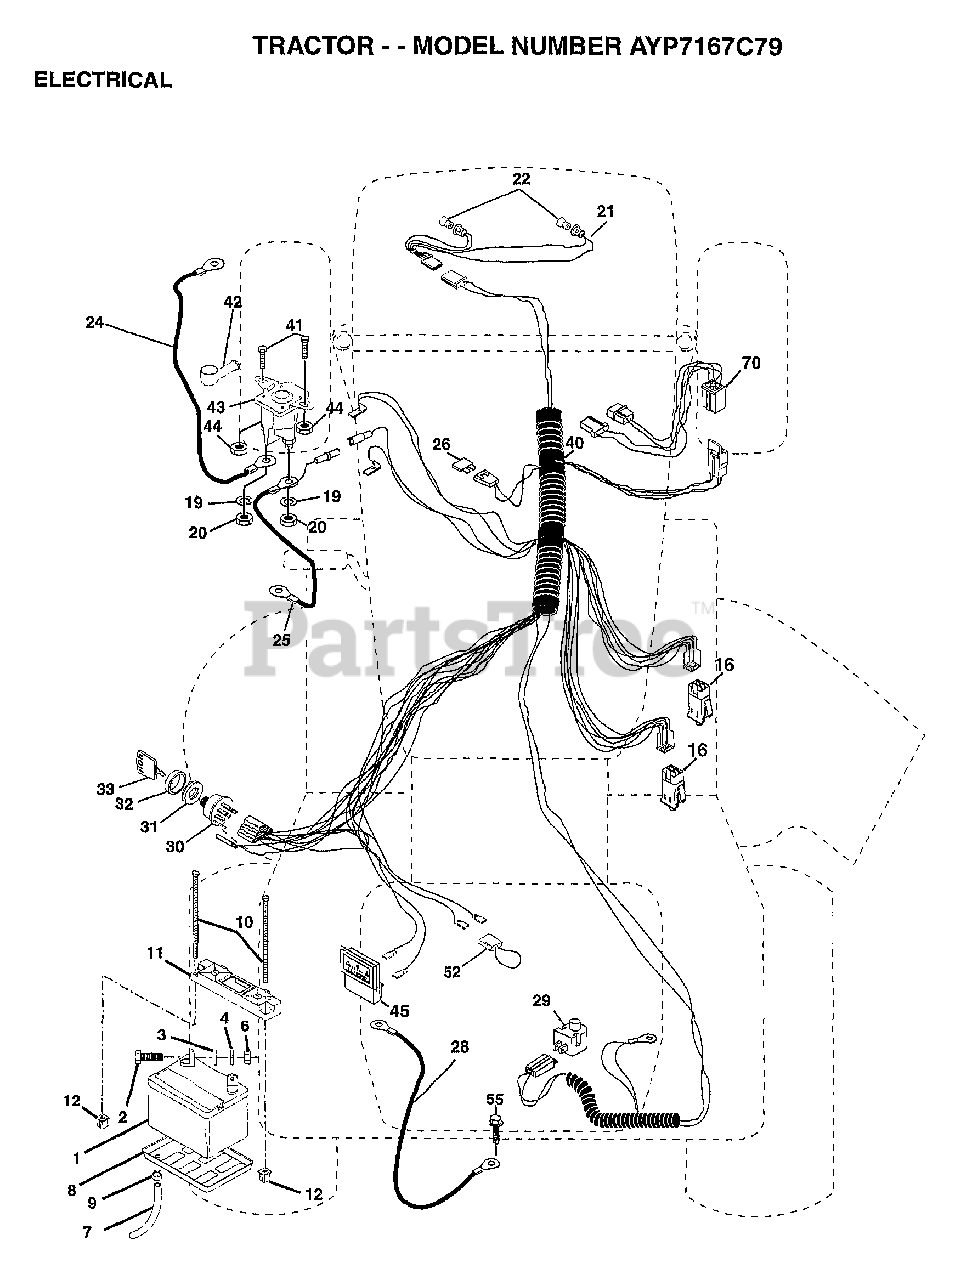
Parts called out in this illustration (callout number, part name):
2	BOLT LT
3	WASHER
4	LOCKWASHER
7	"DRAIN TU T, BATT"
8	"TRAY T, BATTERY"
9	HOSE CLAMP T
11	HOLDDOWN BATTERY
16	SWITCH INTERLOCK
20	NUT
21	"HARNESS,LIGHT SOC"
22	HEADLAMP BULB
24	"CABLE T, BATTERY"
25	CABLE.6GA.22W/16W
26	FUSE HYT
28	CABLE.GRND.6GA.21
29	SWITCH SEAT
30	SWITCH IGN 4POS
31	NUT IGNITION
32	COVER KEY SWITCH
33	KEY
40	HARNESS-IGNITION
41	BOLT HXHD FIN
44	NUT HXKEP 1/4X20
45	AMMETER
52	PROTECTION LOOP
55	SCREW LT
70	HARNESS.ENG.DUAL
